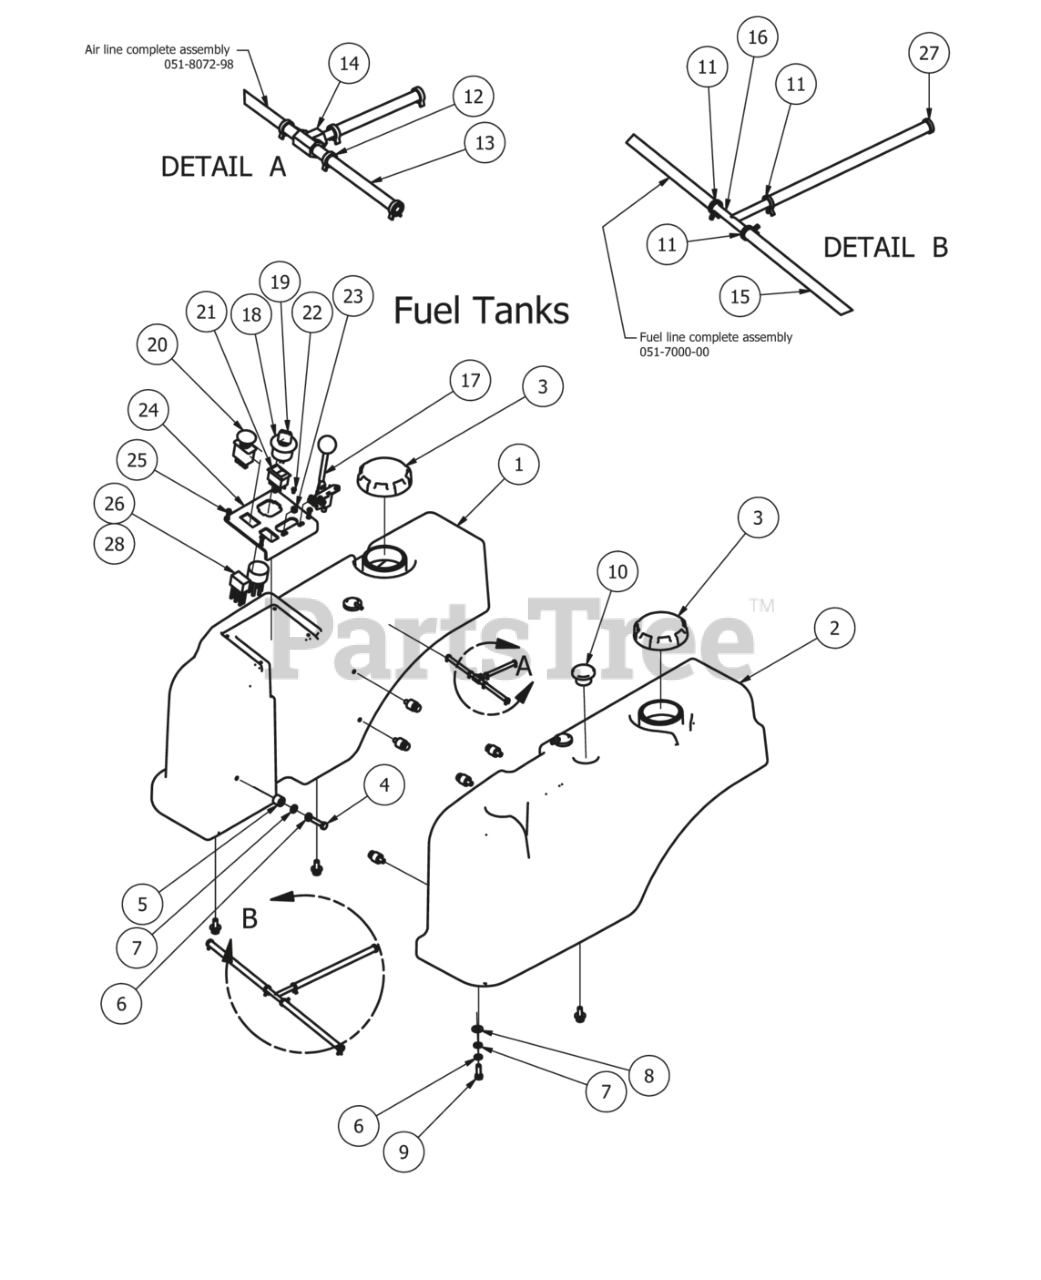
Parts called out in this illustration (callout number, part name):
1	ZT Fuel Tank- Right
2	ZT Fuel Tank- Left
4	5/16 x 1 1/4 Hex Bolt
5	.380x.735x.470 Nylon Spacer
6	5/16" Lock Washer
7	1/4" Flat Washer
8	.360 ID Plastic Washer
9	5/16" x 1" Bolt
10	Fuel Gauge and Grommet
11	1/4 fuel clamp
12	1/4" vinyl hose clamp
13	3/16 vinyl tubing
14	Brass fuel line T
15	1/4" fuel line hose
16	fuel line T
18	Ignition Switch
19	Ignition Key
20	PTO Engager
21	Rocker Deck Lift Switch - 2011 & up
22	10-24 X 5/8 BS C/S 18-8 SS
23	10-24 Nylon Insert Locknut
24	Control Panel ZT
25	10-32 x 3/8" Button Socket Head Bolt
26	Wiring Harness ZT only-2008 and up
27	3/16" Vinyl Hose Clamp
28	Relay Terminal
